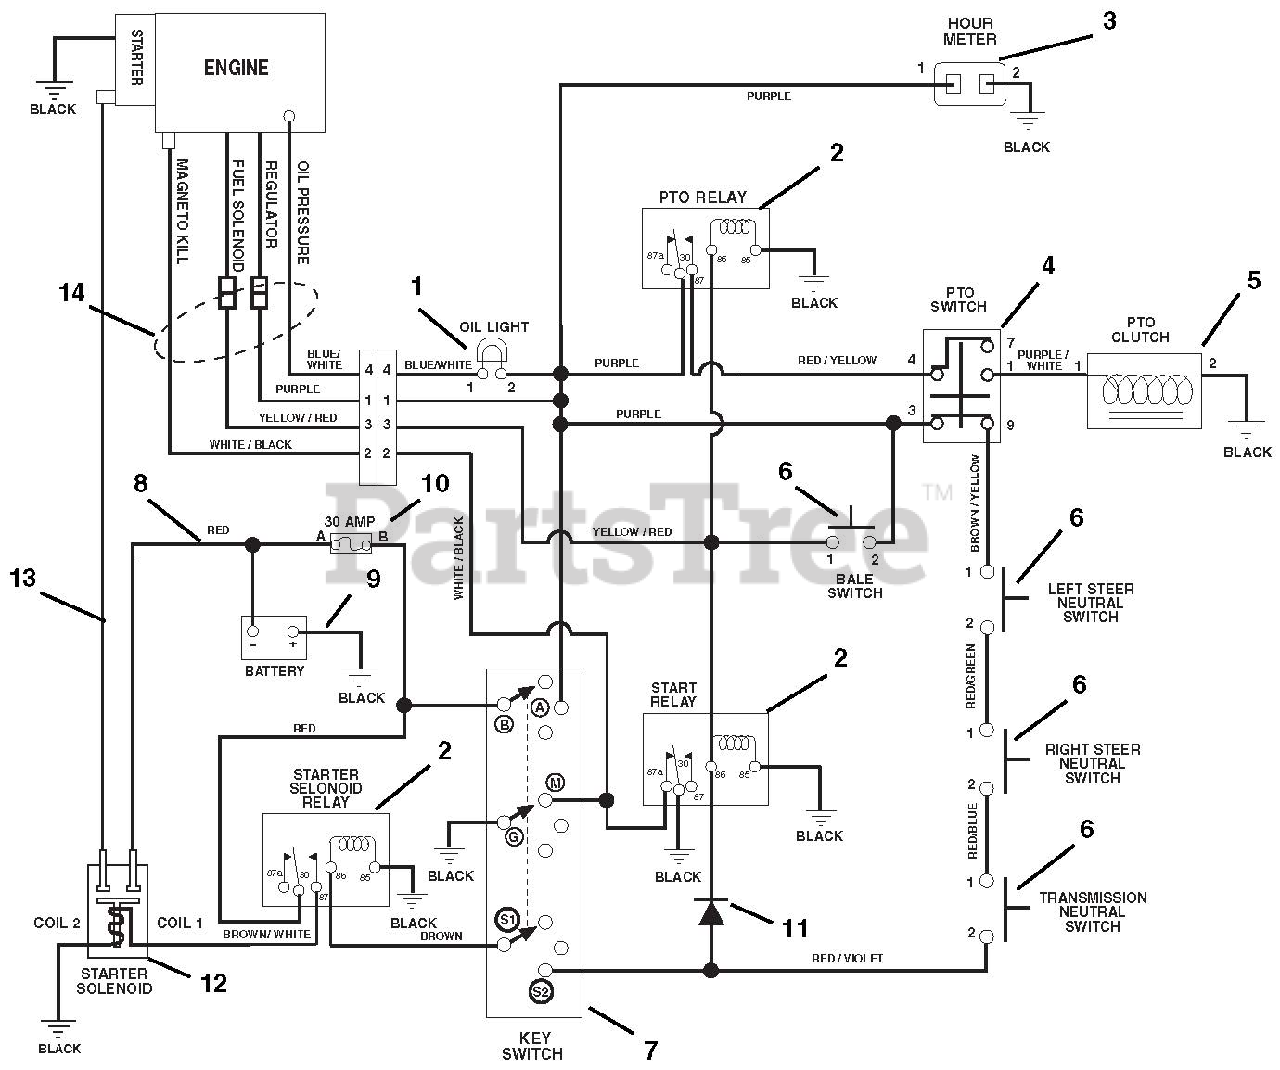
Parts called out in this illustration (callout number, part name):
1	Light, Indicator
2	Relay
3	Hour Meter
4	Switch, Clutch w/ Retainer
5	Clutch, Electric
6	Switch, Bale
7	Key Switch
8	Cable, Battery to Solenoid
9	Cable, Negative Battery
10	Fuse, 30 AMP
11	Molded Diode Plug, 1 AMP
12	Solenoid
13	Cable, Starter 6.75"
14	Adapter, Wire Harness
